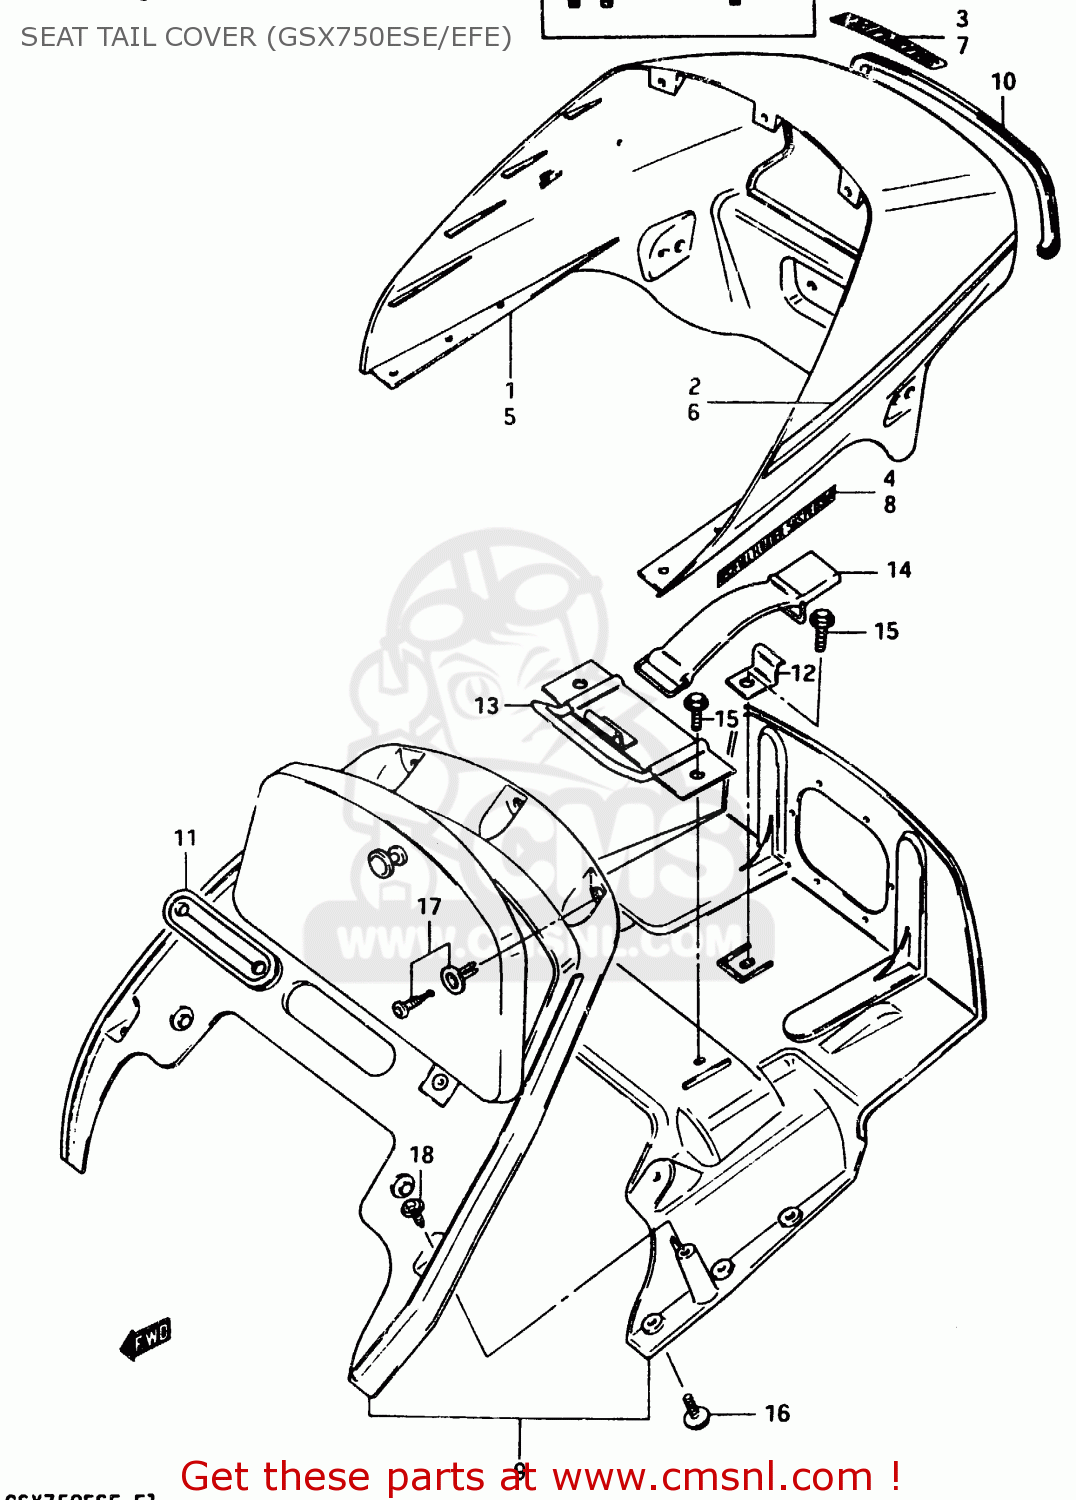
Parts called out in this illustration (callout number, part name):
1	TAIL COVER, SEAT
2	TAPE SET, SEAT TAIL COVER
3	EMBLEM
4	EMBLEM
5	COVER,SEAT TAI
6	TAPE SET, SEAT TAIL COVER
7	EMBLEM
8	EMBLEM
9	FLAP,SEAT TAIL COVER
10	MOLDING,SEAT TAIL COVER
11	GROMMET,SEAT TAIL COVER
12	PLATE,CHAIN LOCK HOLDER
13	PLATE,SEAT HOOK
14	BAND
15	BOLT
16	SCREW
17	CLIP
18	SCREW
